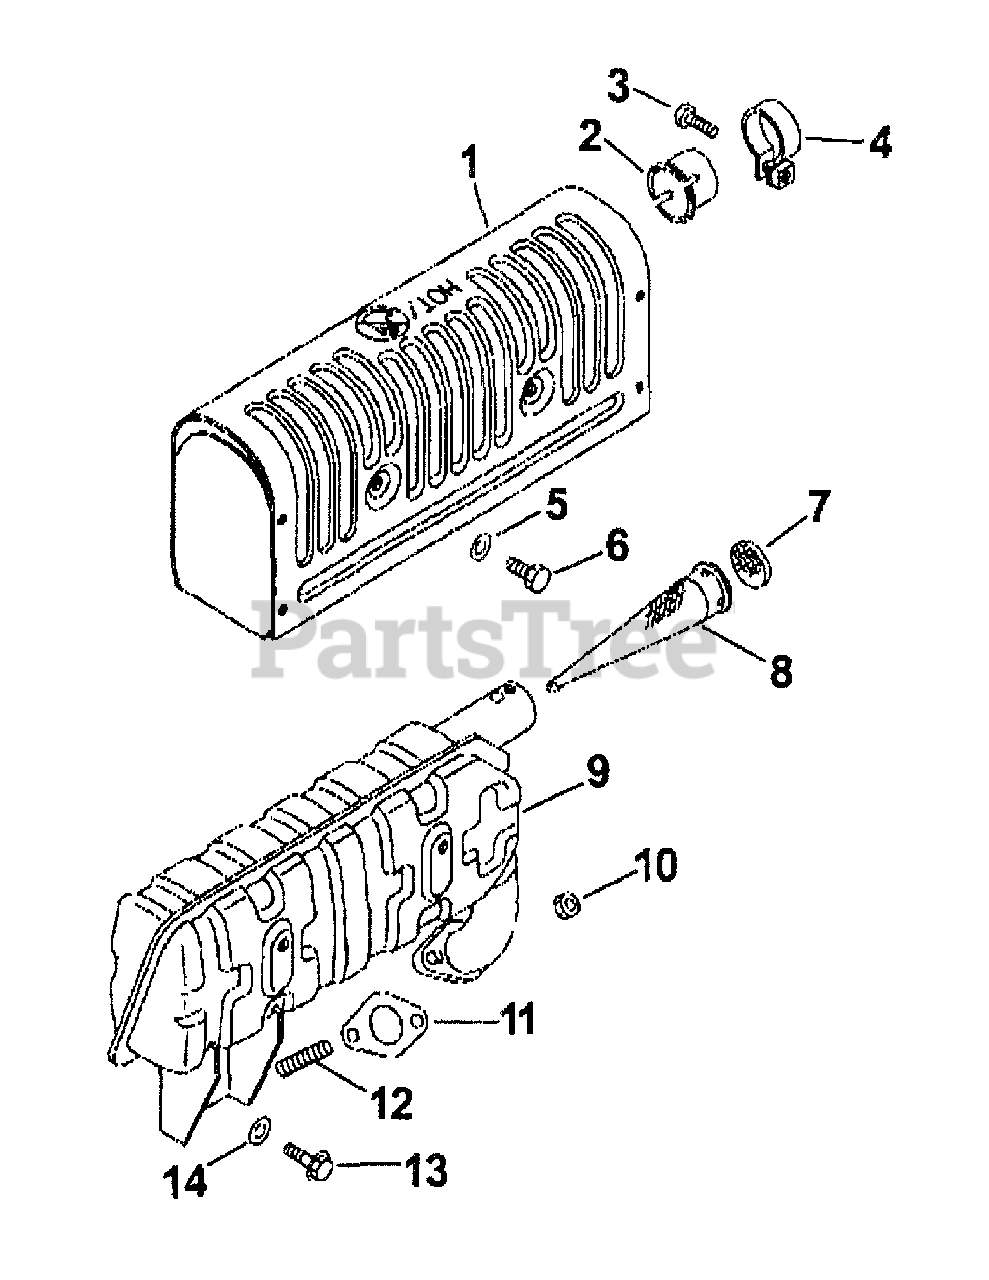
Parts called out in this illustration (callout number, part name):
1	Guard, Muffler
2	Cap, Muffler
4	Band, Exhaust
6	Screw, Hex Flange
8	Arrestor, Spark
9	Muffler
11	Gasket, Exhaust
12	Stud, Exhaust
